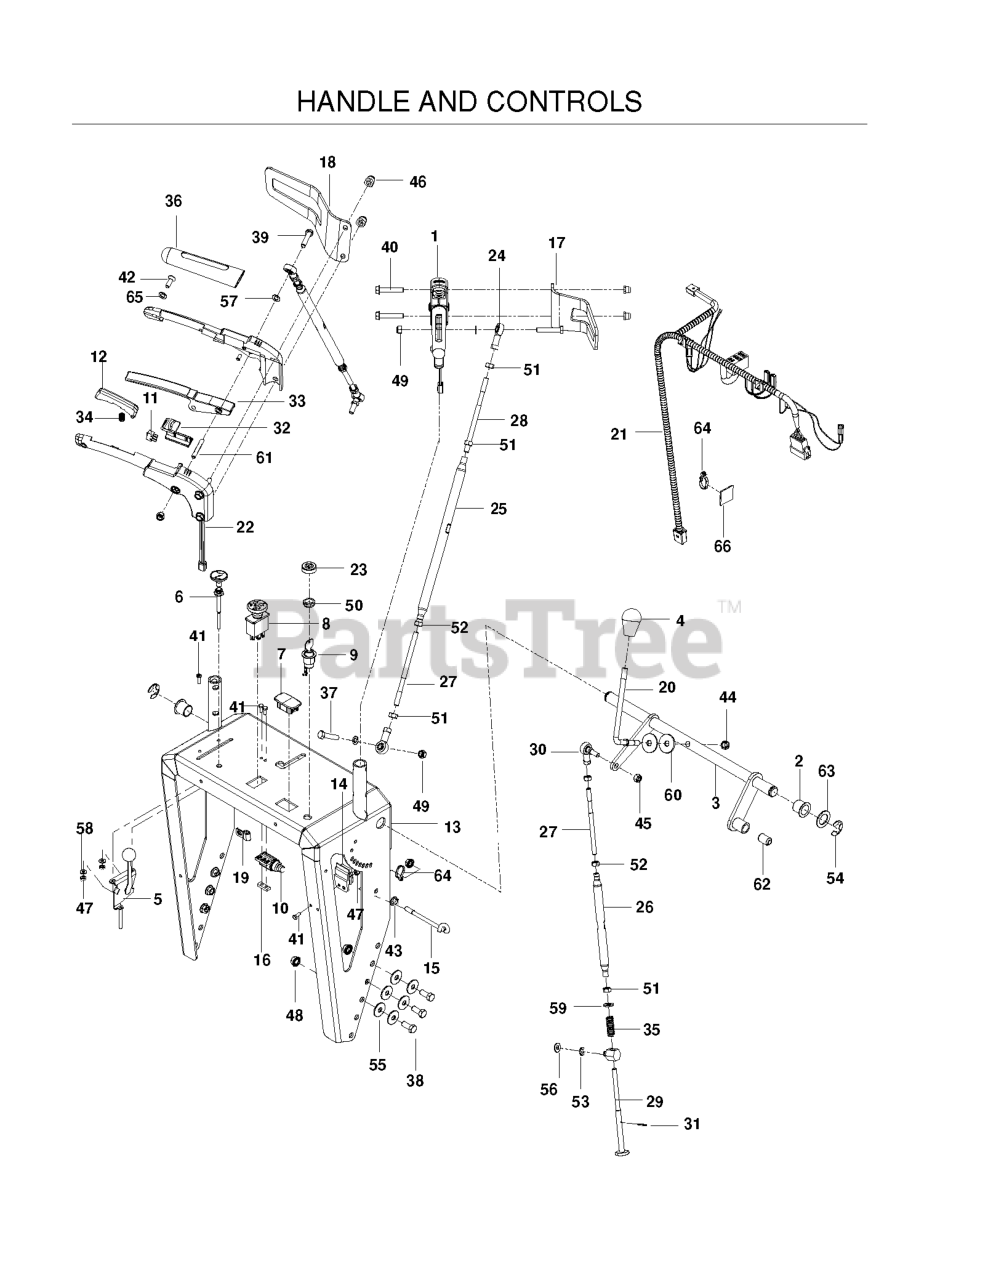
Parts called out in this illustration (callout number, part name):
2	BEARING - FLANGE, 20MM
3	SHAFT, SPEED CONTROL
4	KNOB - SHIFT
5	CONTROL, THROTTLE
6	CABLE, CHOKE, 48"
7	PLUG DASH
8	RP.SWITCH, BLADE
9	KEY SWITCH, COMPLETE
10	SWITCH, NO PLUNGER TYPE
12	OPC ACTUATOR
13	HANDLE W/DECAL
15	GUIDE - ROPE
16	TAPPED PLATE
17	GUARD, HAND - OFFSET RH, PTD
18	GUARD, HAND - OFFSET LH, PTD
19	DOUBLE TUBE CLAMP
20	ROD - SHIFT
21	HARNESS, UPPER HANDLE
22	HARNESS - SWITCH
23	CAP IGNITION NUT
24	ROD END 8 MM, RH
25	TUBE - ADJUSTING
26	TUBE - ADJUSTING
29	ROD - HEADED
30	ROD END 8 MM, W/STUD
31	ROLL PIN - 3 MM
32	LOCK - NEUTRAL
36	GRIP, FOAM
37	BOLT, TAP 5/16-18
38	HCS 3/8-16 X 7/8 GR 5 ZD
39	HCS 5/16C X 1 3/4
40	HHFS 5/16-18 X 1.75 GR8 ZC
41	HCS #10-24 X 1/2
42	SCREW - OVAL HEAD 6MM
43	NUT 5/16C WHIZ
44	NUT HEX 3/8-16 NYLON, THIN
45	NUT M8-1.25 TOP NYL GR10 ZD
46	NUT ACORN 5/16-18
47	NUT 10-24 NYLOC
48	NUT 3/8C WHIZ
49	NUT 5/16 NYLOC
50	DNO IGNITION NUT
51	NUT 8MM X 1.25 HEX ZD
52	NUT, 8MM X 1.25 LEFT HAND
53	E-RING, 20MM
54	E-RING, 10MM
55	SPRING WASHER - .38
56	WASHER 3/8 SAE FLAT
57	WASHER.LOCK.HVY.HLCL.SPR.5/16
58	WASHER #10
59	WASHER, 10MM
60	CONE WASHER
61	PIN - GROOVE 1/4 X 1-1/2
63	BSHG .875 X 1.375 X .074 ZD
64	TIE, PLASTIC
66	MOUNTING BLOCK CABLE TIE
